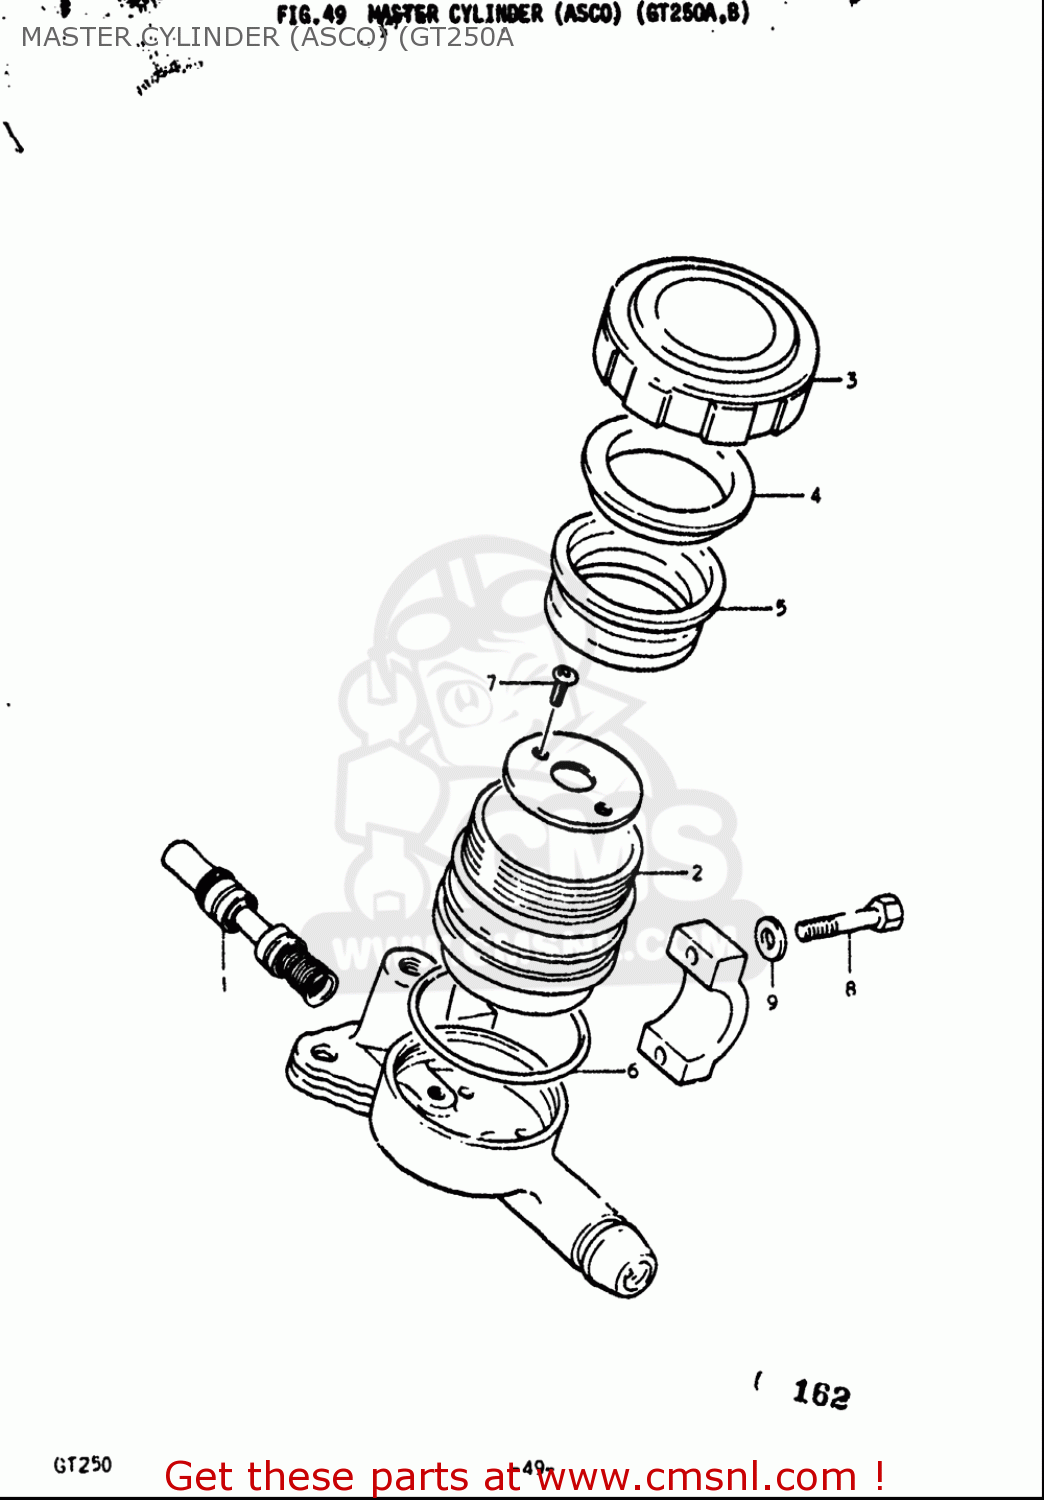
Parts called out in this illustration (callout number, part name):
1	PISTON & CUP SET
2	RESERVOIR
4	PLATE
5	DIAPHRAGM
6	O RING
8	BOLT
9	WASHER
